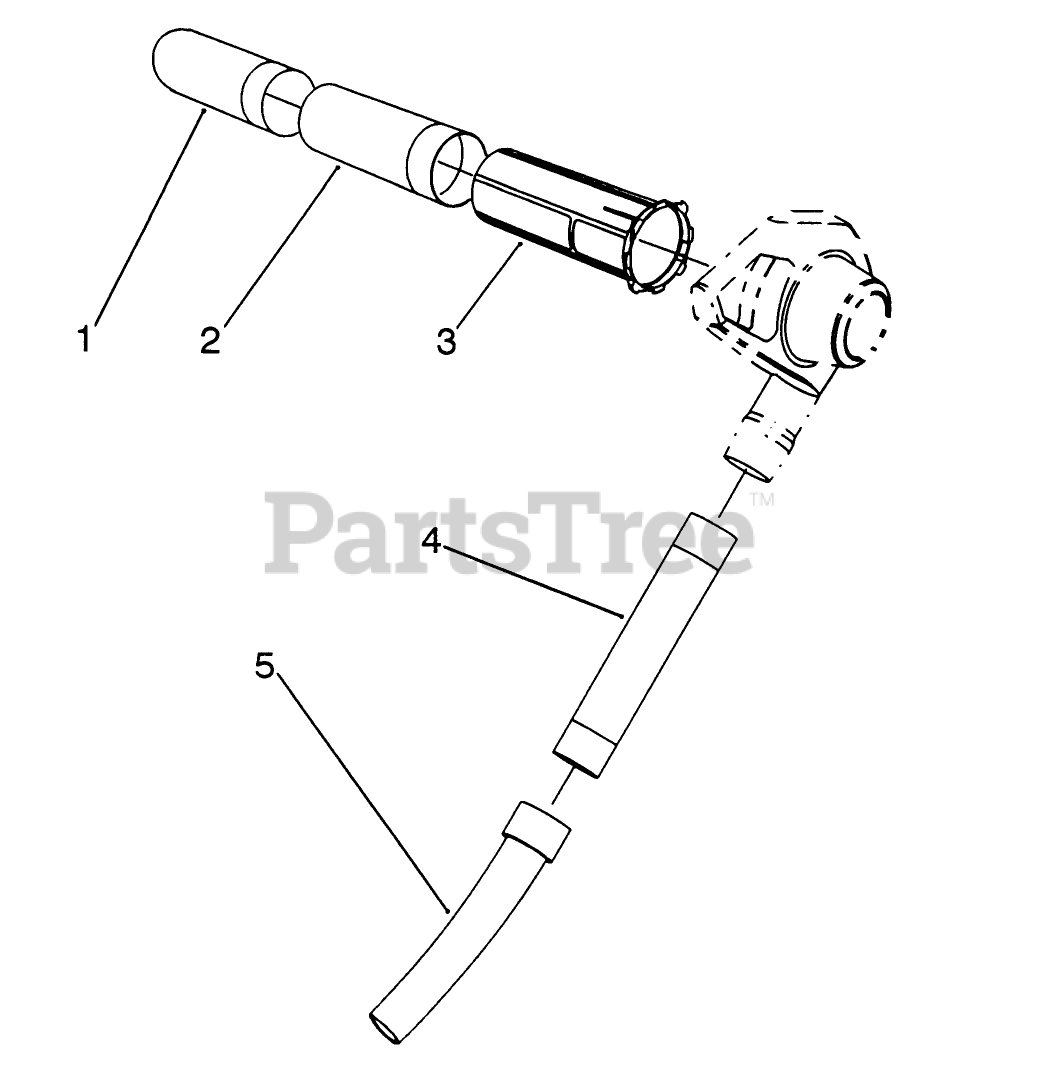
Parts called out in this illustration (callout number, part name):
1	LOWER VAC TUBE
2	MIDDLE VAC TUBE
3	UPPER VAC TUBE
4	BLOWER TUBE
5	MID BL-DISCHARGE TUBE
